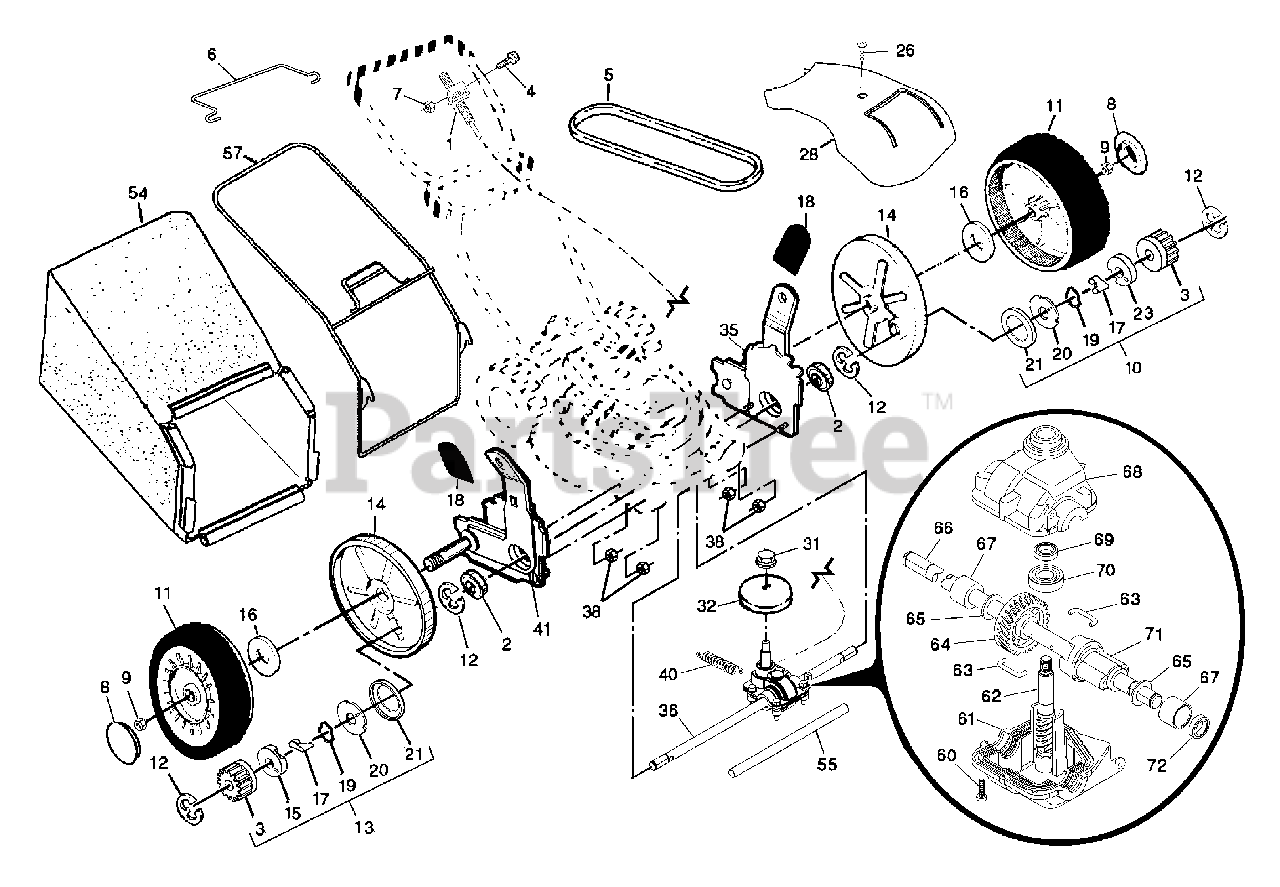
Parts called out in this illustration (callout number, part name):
1	Vari-Speed Drive Control Assembly
2	Bearing, Wheel Adjuster
3	Gear, Pinion
6	Bar, Control, Drive
7	Nut, Hex
8	Hubcap
9	Locknut
10	Pinion Assembly, LH
11	Wheel & Tire Assembly
13	Pinion Assembly, RH
14	Dust Cover
15	Retainer, Drive. RH
16	Washer 1/2 x 1-1/2 x .134
18	Selector Knob
19	Spring, Torsion
20	Disc, Drive
21	Seal, Pinion
23	Retainer, Drive, LH
26	Pan Head Tapping Screw #10-24 x 2-3/4
28	Drive Cover
31	Hex Flange Nut
32	Drive Pulley
35	Kit, Wheel Adjuster, LH
36	Gear Case Assembly, Complete
38	Locknut 1/4-20
40	Spring
41	Kit, Wheel Adjuster, RH
54	Grassbag Assembly
55	Driveshaft Cover
57	Frame
61	Case, Lower
62	Shaft, Input
63	Wire, Formed
64	Gear, 27 Teeth
66	Shaft, Output
68	Case, Upper
69	Seal, Input Shaft
70	Bearing, Ball
72	Seal, Output Shaft
